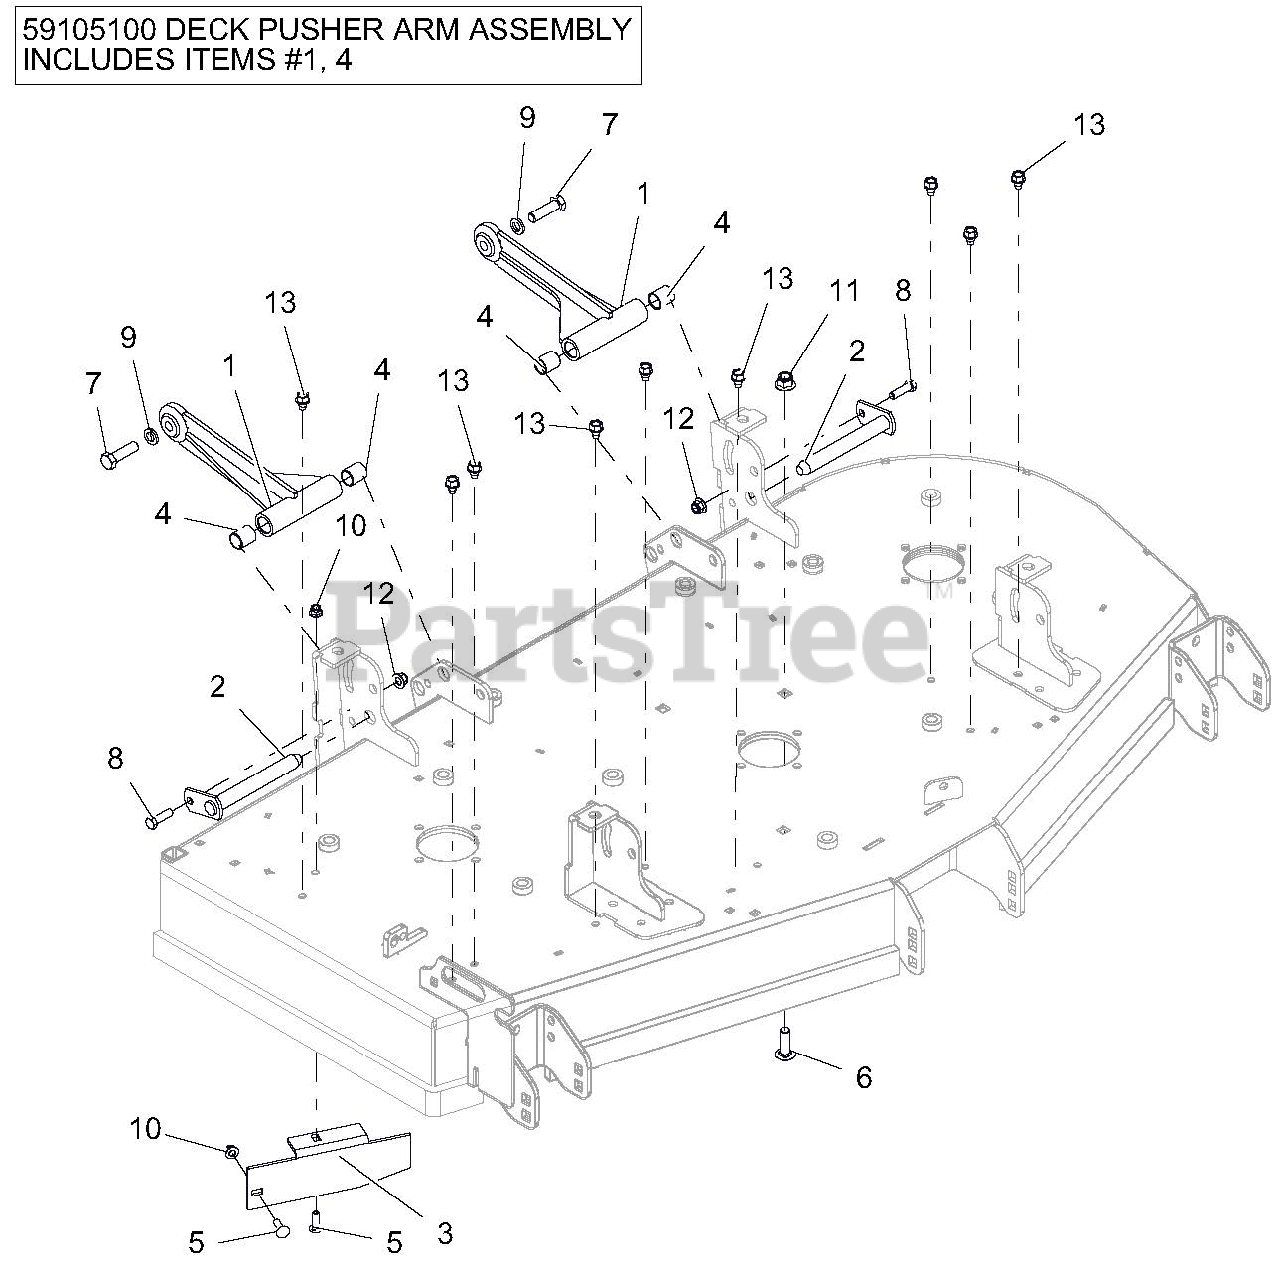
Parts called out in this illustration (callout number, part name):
1	WLDMT, DECK PUSHER ARM
2	WLDMT, MOWER MTG. PIN
3	BAFFLE, 52" DISCHARGE-RED
4	BRG, .75 X .875 X 1.00
5	BLT-RDHDSQSHNK .31-18X1.00 G5 Y
6	BLT-RDHDSQSHNK .50-13X1.50 YWZC
7	BLT-HEX .50-13X1.75 GR5 YWZC EP80
8	BLT-HEX .38-16X1.25 GR5 YWZC
9	WSHR-LK .50X.125 REG YWZC
10	NUT-LK-NYL-FLG .31-18 YWZC
11	NUT-LK-NYL-FLG .50-13 YWZC
12	NUT-LK-NYL-FLG .38-16 YWZC
13	SCR-TAP .38-16X.50 HWH TR YWZ
14	DECK PUSHER ARM ASSEMBLY
